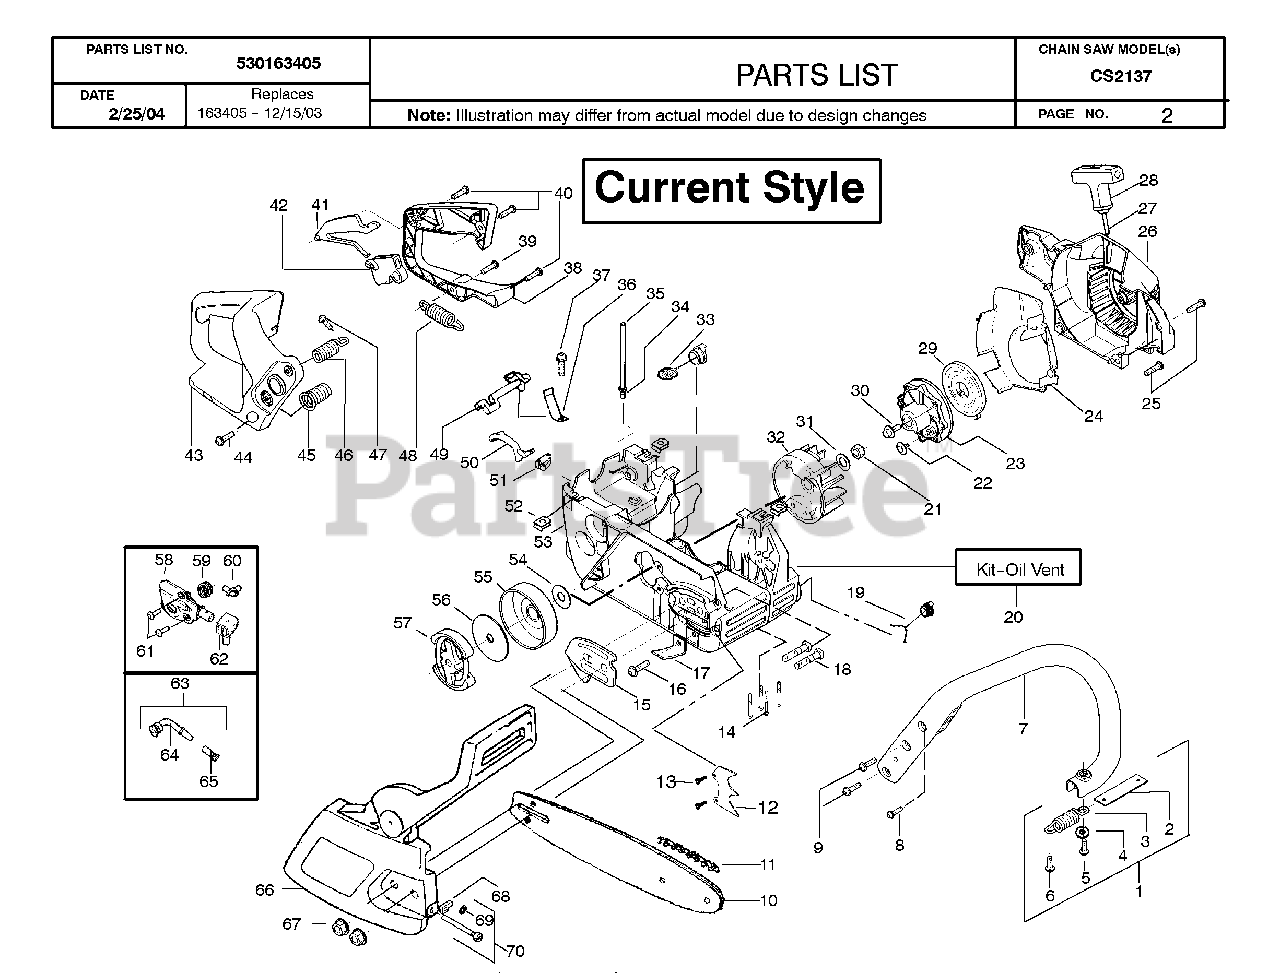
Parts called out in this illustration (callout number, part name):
1	ASSY-ISOLATOR
2	STRAP
3	SPRING
4	WASHER
7	HANDLE
12	SPIKE 36/41
17	CHAIN CATCHER 36/41
19	OIL TANK CAP
20	KIT-OIL CHECK VALVE
21	NUT-FLYWHEEL
23	STARTER PULLEY
24	AIR BAFFLE
25	SCREW,STRTR CVR 36/41
28	HANDLE STARTER
31	WASHER-FLYWHEEL
32	FLYWHEEL
33	TANK CAP
34	FUEL LINE FITTING
39	SCREW-10-14 X 13/16 (PL
40	SCREW,FRONT HBAR 36/41
41	THROTTLE LOCK
42	THROTTLE TRIGGER
45	SPRING
46	SPRING
48	SPRING
54	DUST COVER 36/41
55	CLUTCH DRUM ASSY
56	FRICTION DISC,CLUTCH 36/41
57	CLUTCH ASSEMBLY
59	WORM GEAR
64	PICK-UP OILER
65	SCREEN/FILTER
68	ADJUST PIN,BAR 36/41
